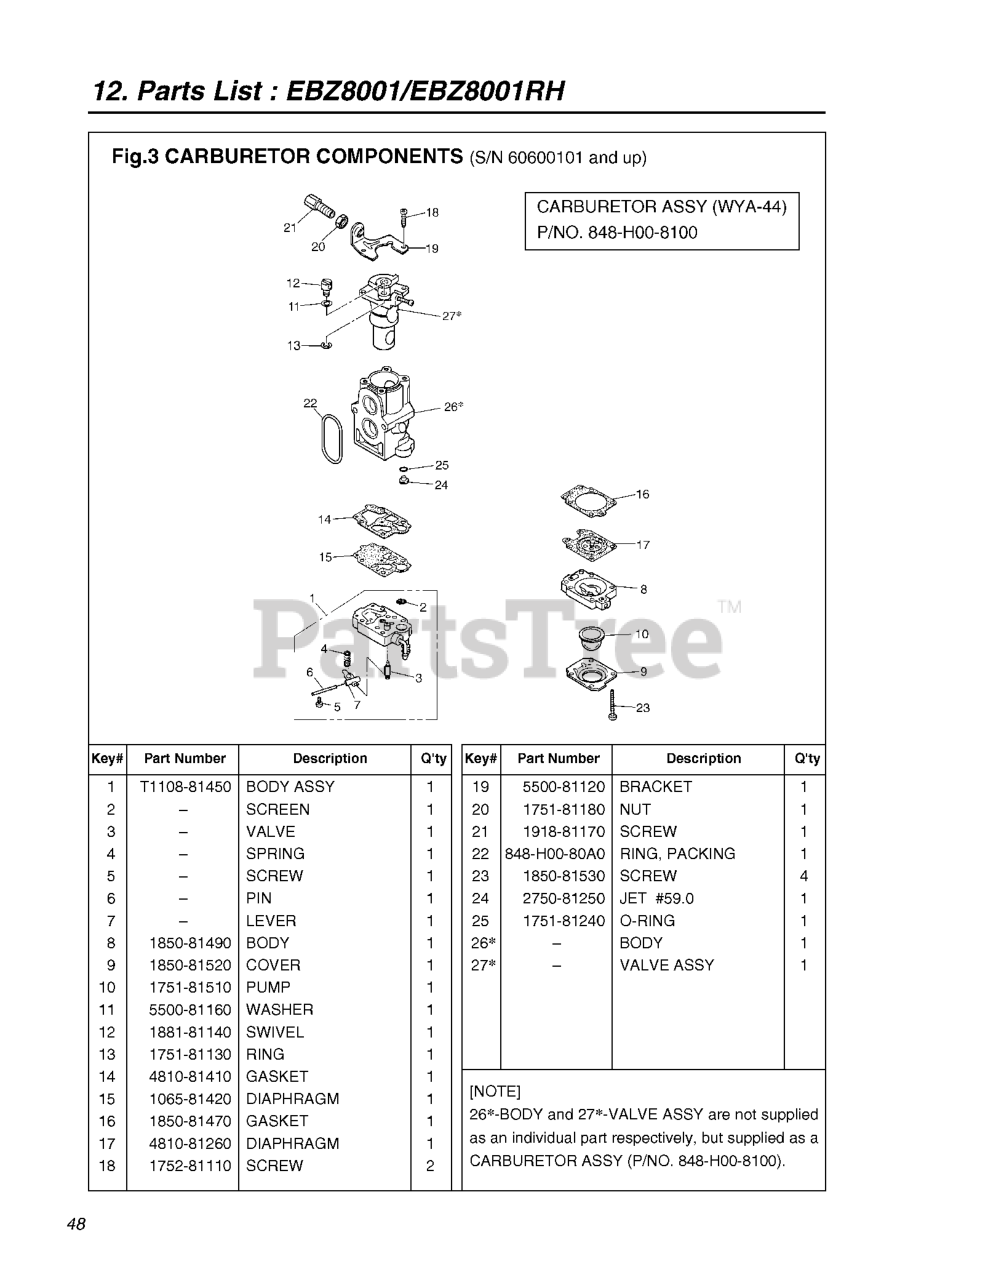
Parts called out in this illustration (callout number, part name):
1	BODY-A-PUMP
9	1OVER
11	WASHER
12	SWIVEL
13	RING
15	DIAPHRAGM
18	SCREW
19	BRACKET
20	NUT
21	ADJUSTER
22	RING
26	CARBURETOR-A
27	CARBURETOR-A
